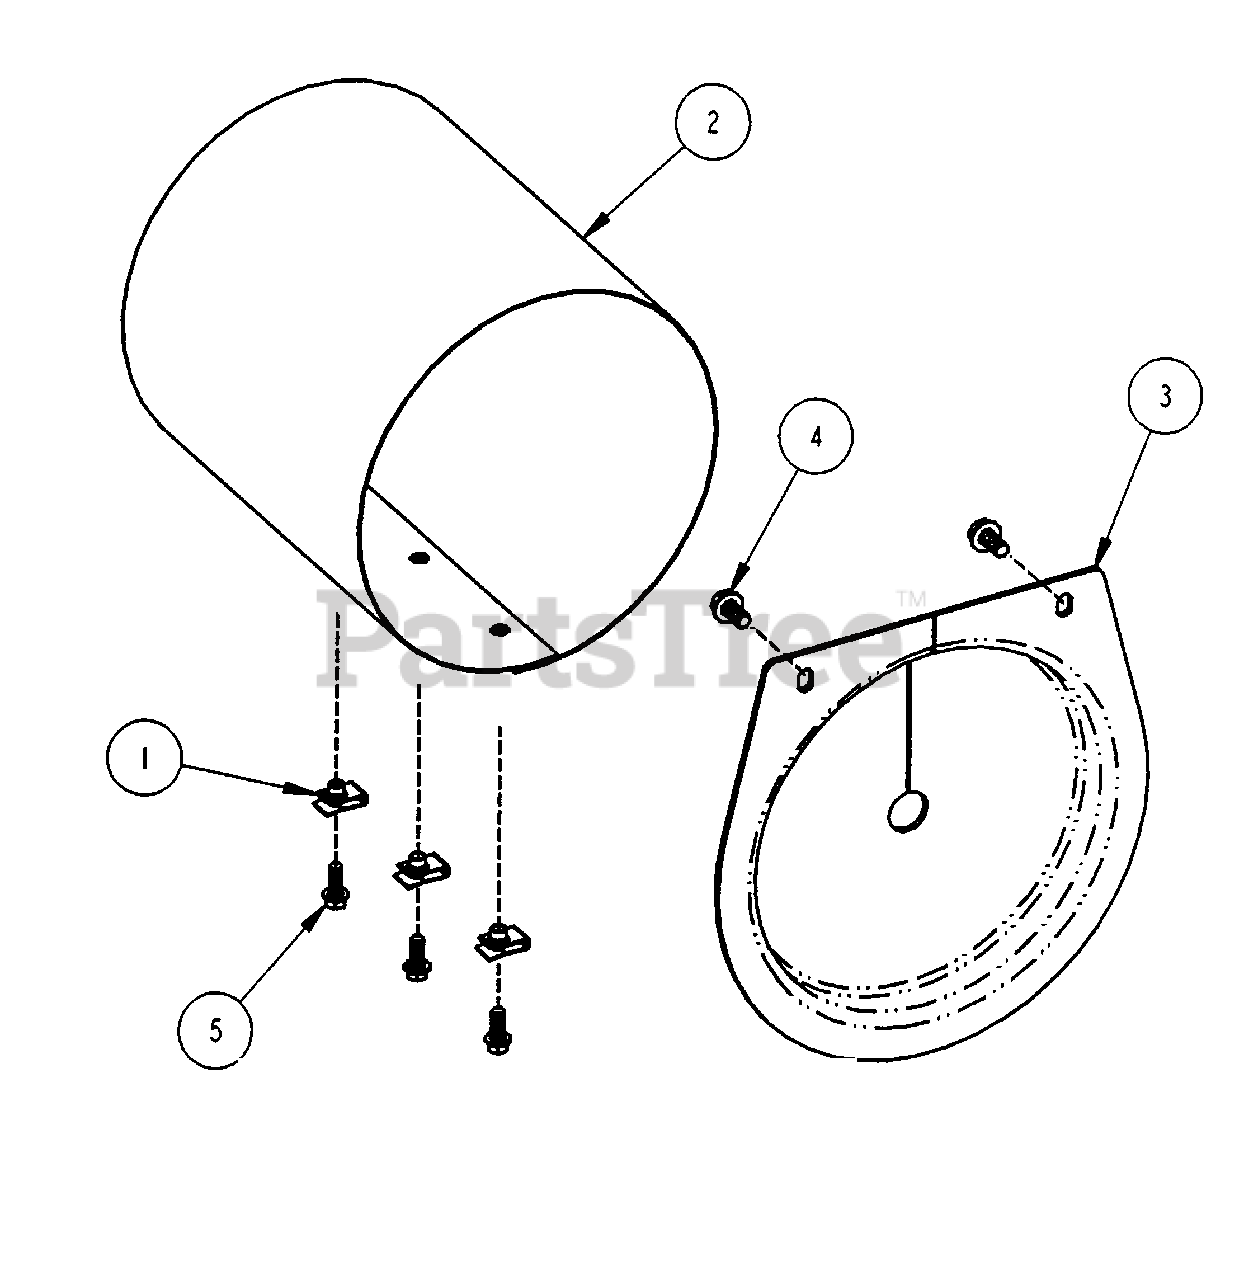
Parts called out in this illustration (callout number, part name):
1	U-NUT, 1/4-20
2	SCREEN, Air Intake
3	MOUNT, Air Intake
4	SCREW, 5/16-18 x 5/8" Hex Fl. Self-Tap
5	SCREW, 1/4-20 Hex Flange Lock
